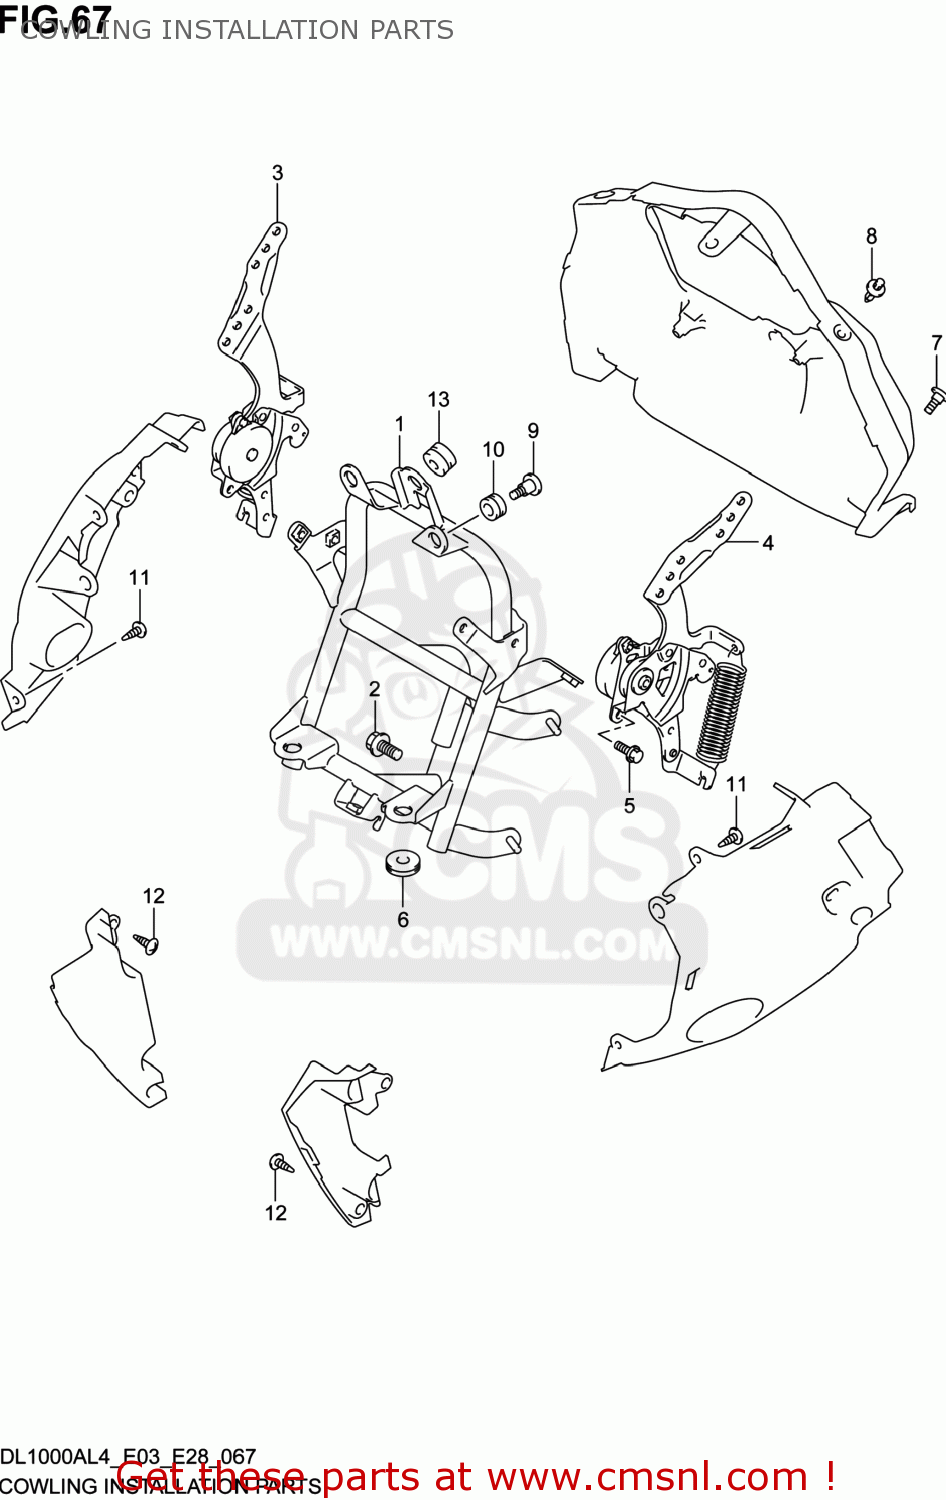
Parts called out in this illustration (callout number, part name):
1	BRACE,COWLING
2	BOLT
3	BRACE,WINDSCREEN,R
4	BRACE,WINDSCREEN,L
5	BOLT(6X16)
6	CUSHION
7	SCREW(6X16)
8	CLIP(BLACK)
9	SCREW(6X20)
10	CUSHION
11	SCREW
12	SCREW
13	CUSHION,SPEEDOMETER
